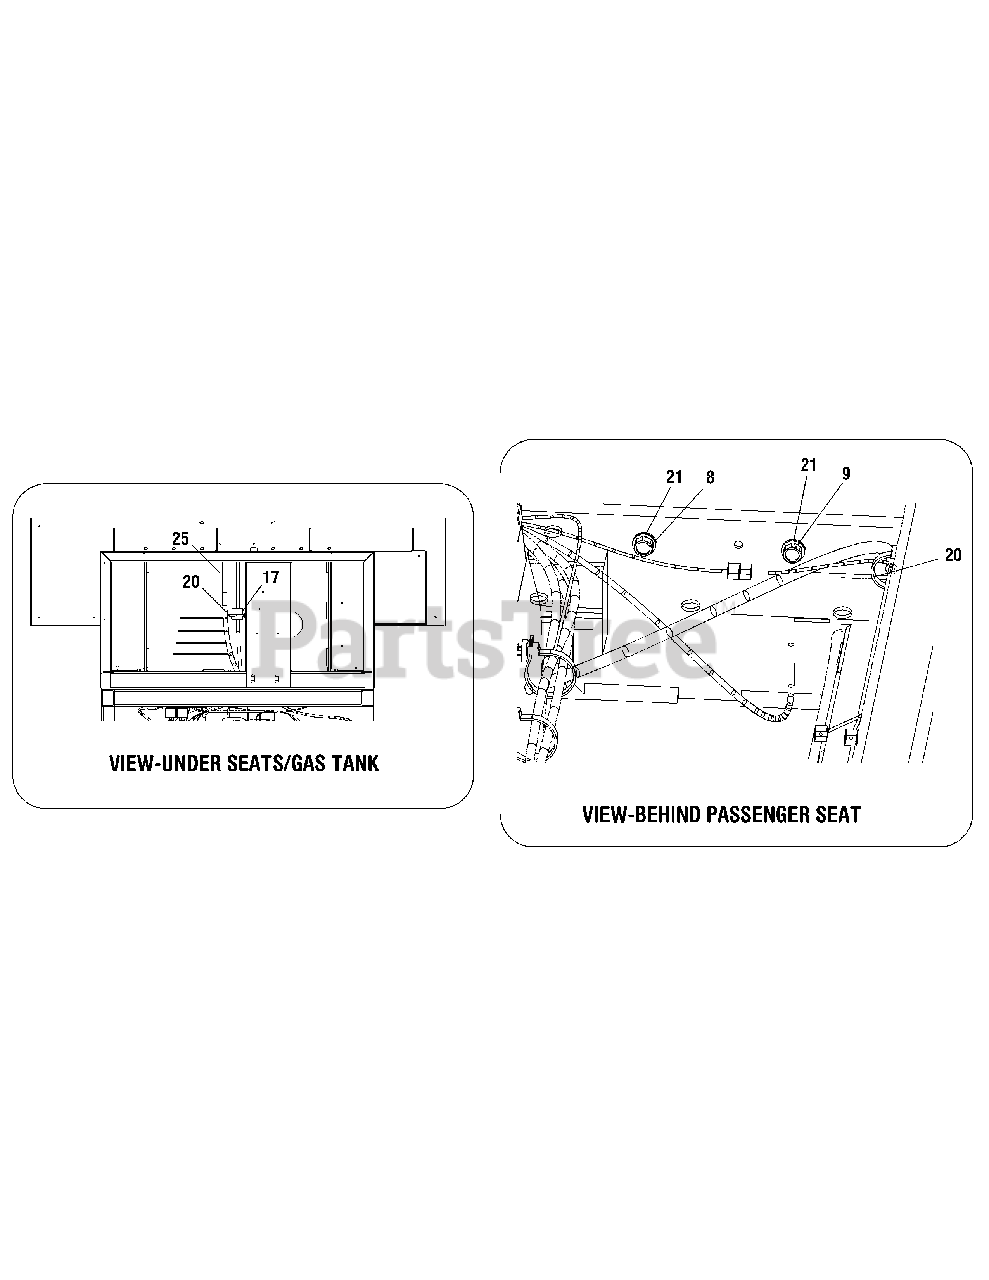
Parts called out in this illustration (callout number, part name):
1	Bracket, Retainer Hook
2	Harness Assembly, Starter
3	Harness Assembly, Motor Ground
4	Screw, 1/4-20 x .50
5	Screw, Self-tapping, 1/4-20 x 0.500
6	Screw, Self-tapping, 5/16-18 x .50
7	Screw, Hex Carriage, 1/4-20 x .75
8	Screw, Self-tapping, 1/4-20 x 1.000
9	Screw, #10-24 x 0.75
10	Nut, Hex Sems, 1/4-20
11	Cover, Protective
12	Strap, Battery
13	Cable Tie, 3/16 x .05 x 7.4
14	Control, Shaft
15	Harness, Utility Main
16	Harness, Motor Kohler
17	Control, Reverse
18	Switch
19	Battery
20	Cable Tie, .19 x 8.39 Tree Mount
21	Lock Washer, 1/4
22	Hourmeater Jumper Harness
23	Pop Rivet.188
24	Lock Washer 1/4 exterbak
25	Fuel Line Hose
